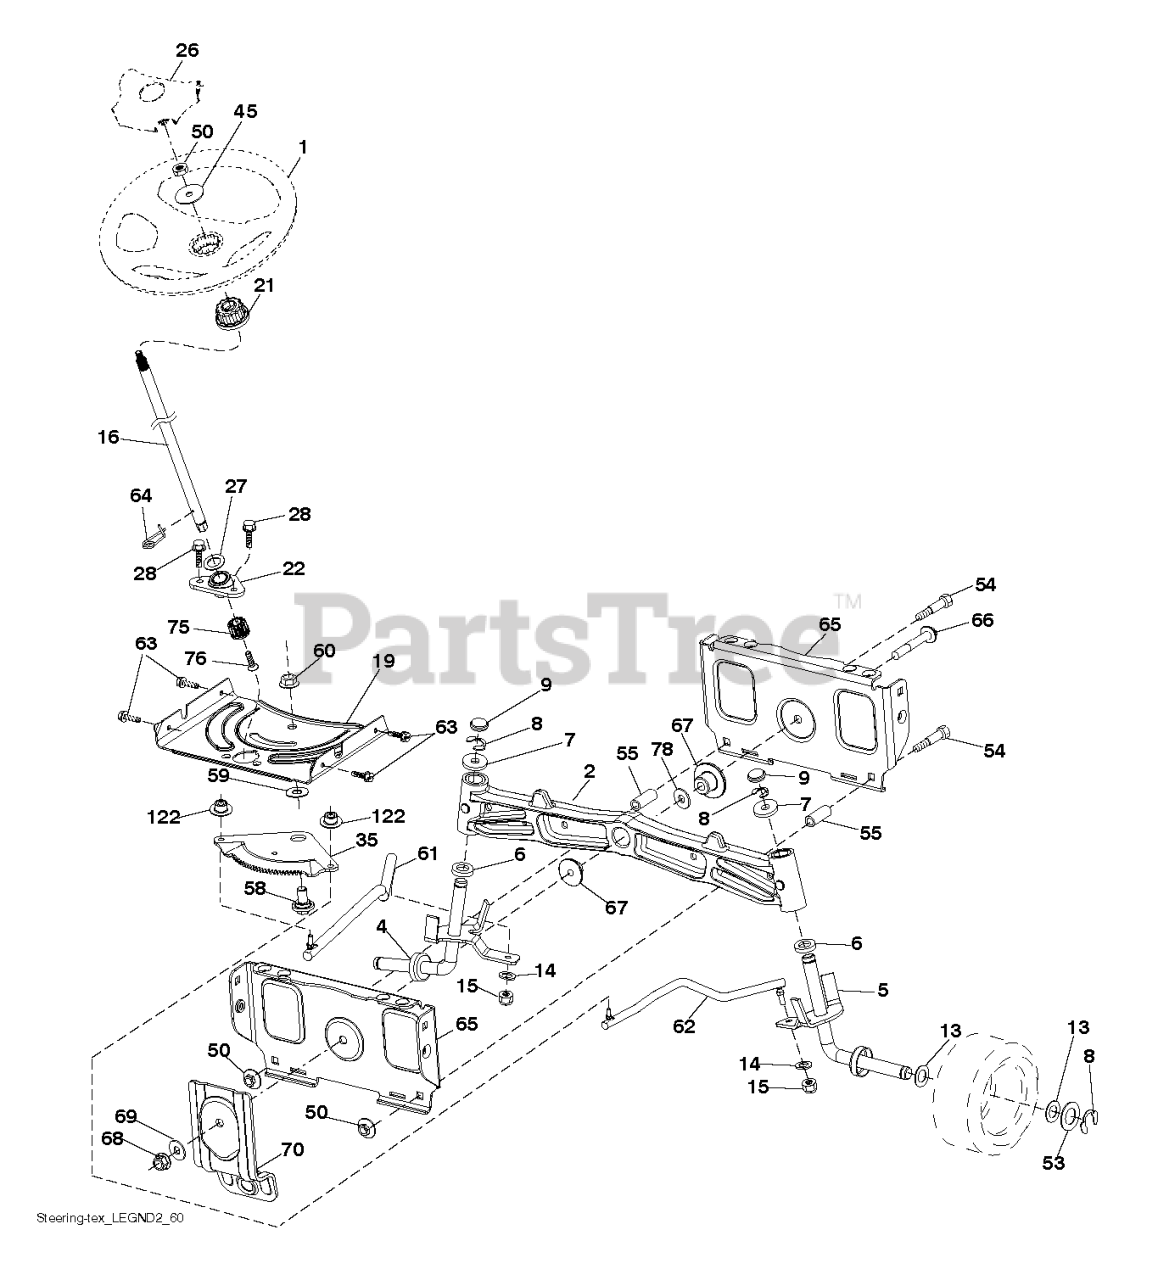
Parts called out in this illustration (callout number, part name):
1	WHEEL.STEER.HUSQ.SR.498.OVMLD
2	AXLE.CAST.IRON
4	SPINDLE.WELDED.LH.16"TEX
5	SPINDLE.WELDED.RH.16"TEX
6	THRUST WASHER
9	CAP.SPINDLE.BLACK
14	WASHER, LOCK 3/8
15	NUT CROWNLOCK 3/8-24
16	SHAFT.STEER.2HIGH.SPLND.PLATED
19	PLATE.STEER.DDL.NLT/NG
21	ADAPTER.WHEEL.STEER.SPLND.ALUM
22	BEARING.SHAFT.STEER.LOWER.625
26	INSERT.CAP.WHL.STRG.HUSQ.PREM
28	SCREW, 3/8-16X3/4
35	GEAR.SECTOR.PLATE.DDL.
45	WASHER.3/8ID.2-3/8OD.12GA.PLTD
50	NUT LOCK FLG 3/8-16 UNC
53	WASHER.HARDENED
55	SPACER.BRACE.AXLE
58	BOLT.SHOULDER.SECTOR.P
59	WASHER.THURST.SECTOR.S
60	NUT FLANGE LOCK 5/8-11
61	DRAGLINK.LH.BALLSTUD.D
62	DRAGLINK.RH.BALLSTUD.D
63	SCREW
64	RETAINER.CLIP.SPRING.S
65	BRACE.AXLE.FRONT.NLT/N
66	BOLT HEX FGHD 7/16-14 X 3 SERR
67	BUSHING.PM.FRONT AXLE
68	NUT.LOCK.FLANGE.7/16
69	WASHER.1.5X.505X.118
70	BRACKET.FRT.DECK.SUSP.RR.MT431
75	PINION.ZINC PLATED
76	SCREW HEAD SOCKET LRVB
78	THRUST WASHER
122	CAP.GEAR.SECTOR.TEX
